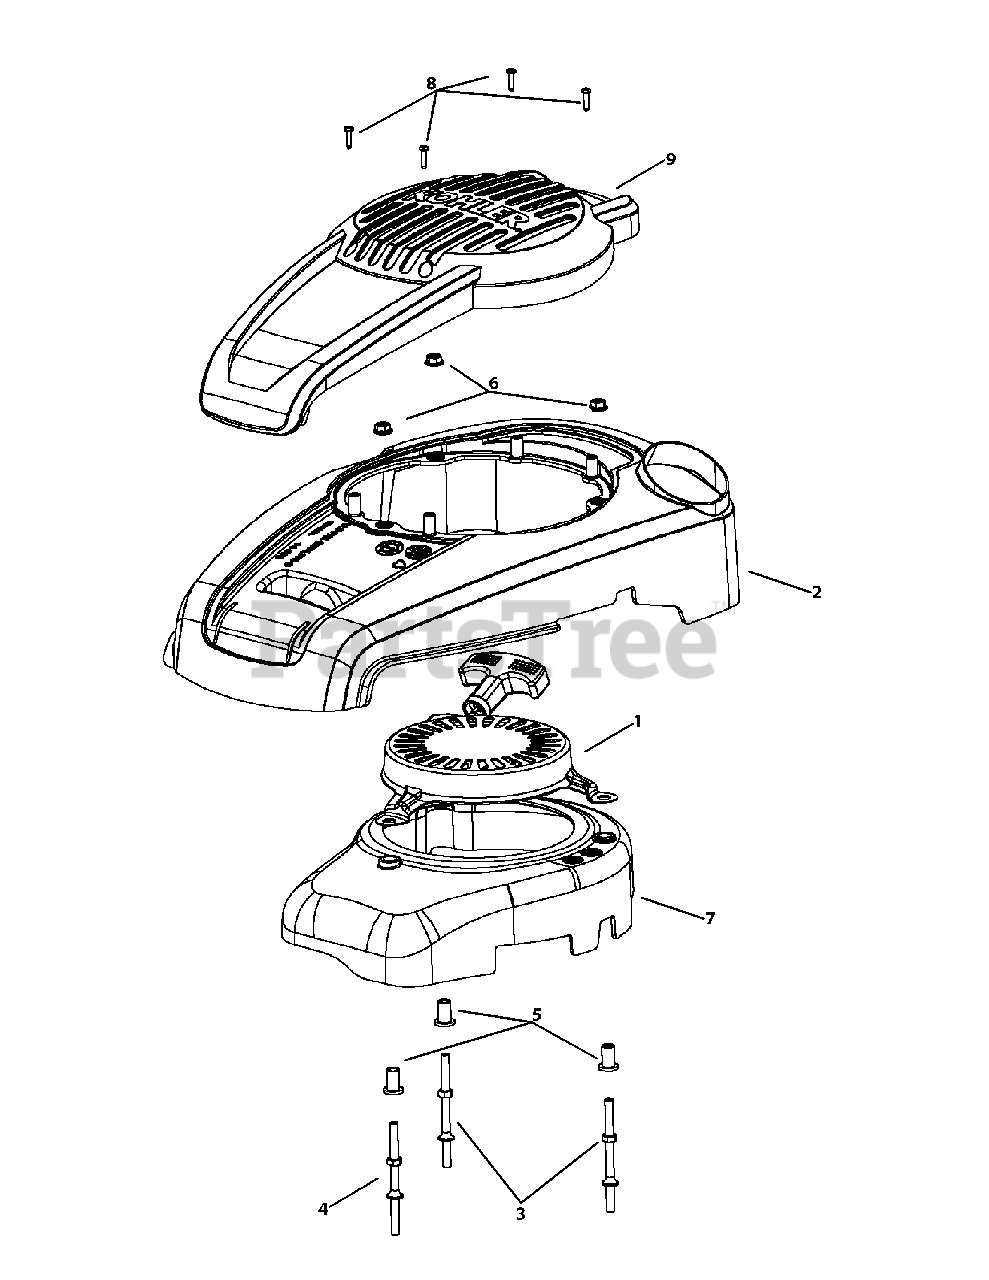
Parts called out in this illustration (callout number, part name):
1	Retractable Starter Assembly
2	Engine Cover (Black)
3	Stud
4	Stud
6	Hex Flange Nut, M6
7	Blower Housing
8	Hi-Lo Screw, #15
9	Engine Cover Insert (Black)
